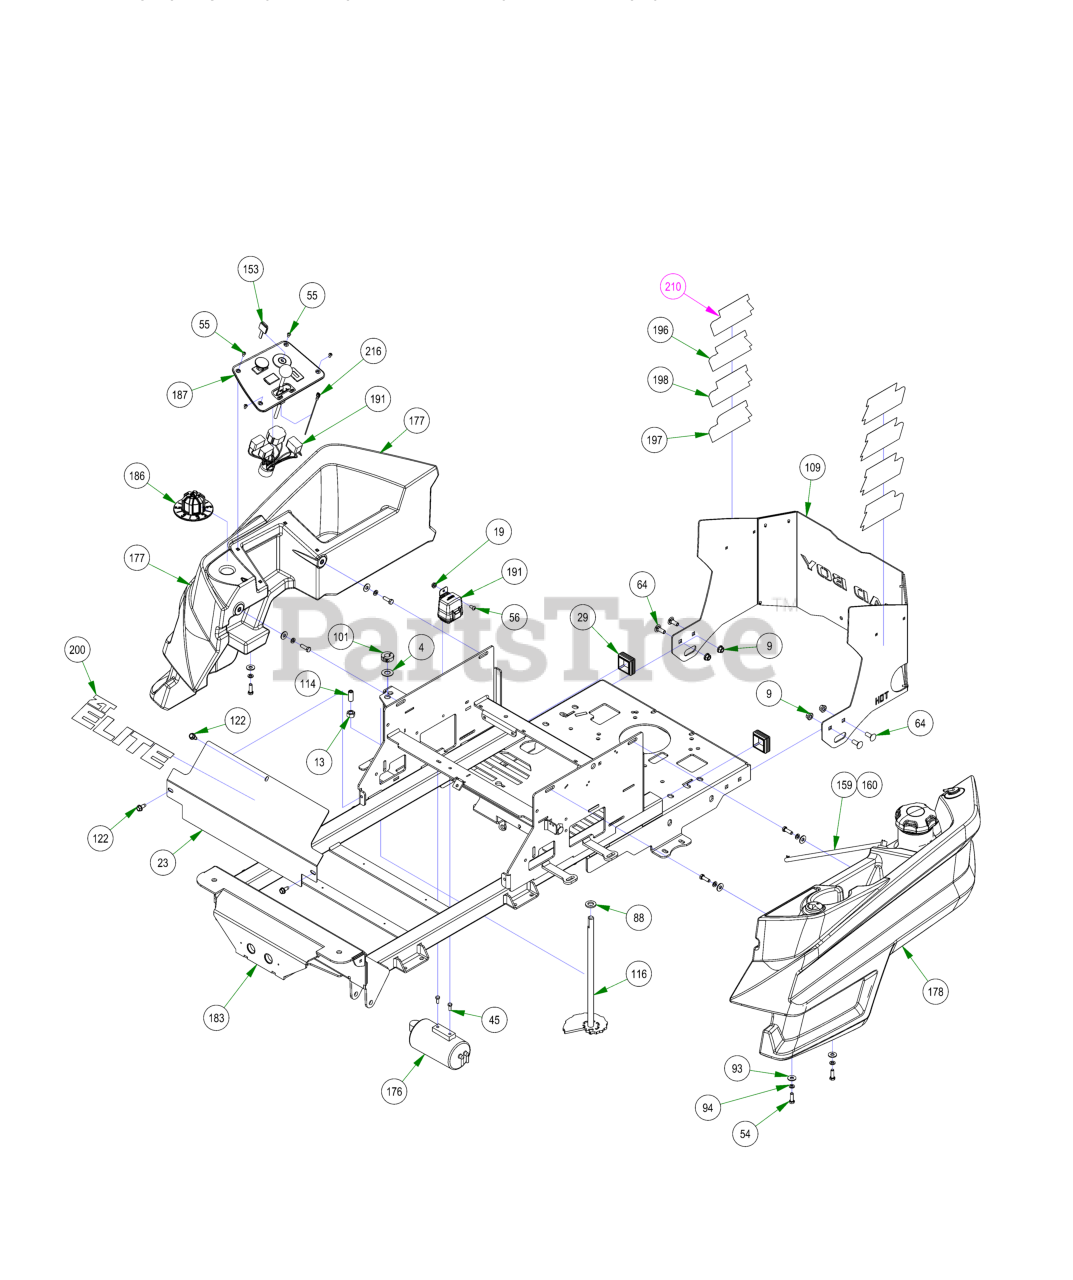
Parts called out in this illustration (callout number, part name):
4	.625 ID x 1.250 OD x .062 THK F/W Nylon
9	3/8-16 NYLON INSERT FLANGE LOCKNUT (GR.F) ZINC
13	1/2-13 HEX NUT ZINC
19	1/4-20 HEX SERRATED FLANGE NUT HARD/ZINC
23	2021 ZT Cooler Cover Painted
29	2X2 Frame Plug
45	M6-1.0 X 16MM DIN 933 HEX TAP BOLT (CL 8.8) ZINC
54	5/16-18 X 1 HEX CAP SCREW (GR.5) ZINC
55	10-32 X 3/8 BUTTON SOCKET CAP SCREW 18-8 STAINLESS
56	1/4-20 X 1/2 BUTTON SOCKET CAP SCREW 18-8 STAINLESS
64	3/8-16 X 1 CARRIAGE BOLT (GR.5) ZINC
88	.635 ID X 1.120 OD X .140 THICK FLAT WASHER NYLON
93	5/16 USS FLAT WASHER (7/8 OD) ZINC
94	5/16 SPLIT LOCKWASHER ZINC
101	5/8" Split Collar
109	2022 ZT Elite Rear Cover Assembly
114	Dial Rod Plunger
116	ZT Deck Height Bar Assembly
122	5/16-18 X 3/4HEX WASHER SLOT (F) TCS ZINC
153	Ignition Key
159	15" Fuel Line Assembly
160	37" Fuel Line Assembly
176	ZT/Mav EPA Cannister Assy
177	2021 Maverick Right Side Tank
178	2021 Maverick Left Side Tank
183	2022 Suspension ZT Frame - Painted
186	MZ/ZT Deck Height Dial
187	2019 ZT/Maverick Control Panel Assembly
191	Wiring Harness
196	2021 ZT Elite 747cc Back Plate Cluster
197	2021 ZT Elite 726cc Back Plate Cluster
198	2021 ZT Elite 725cc Back Plate Cluster
200	2017 ZT Elite Cooler Cover Decal
216	2017 MZ/ZT/MAV Tach Wire Assy
